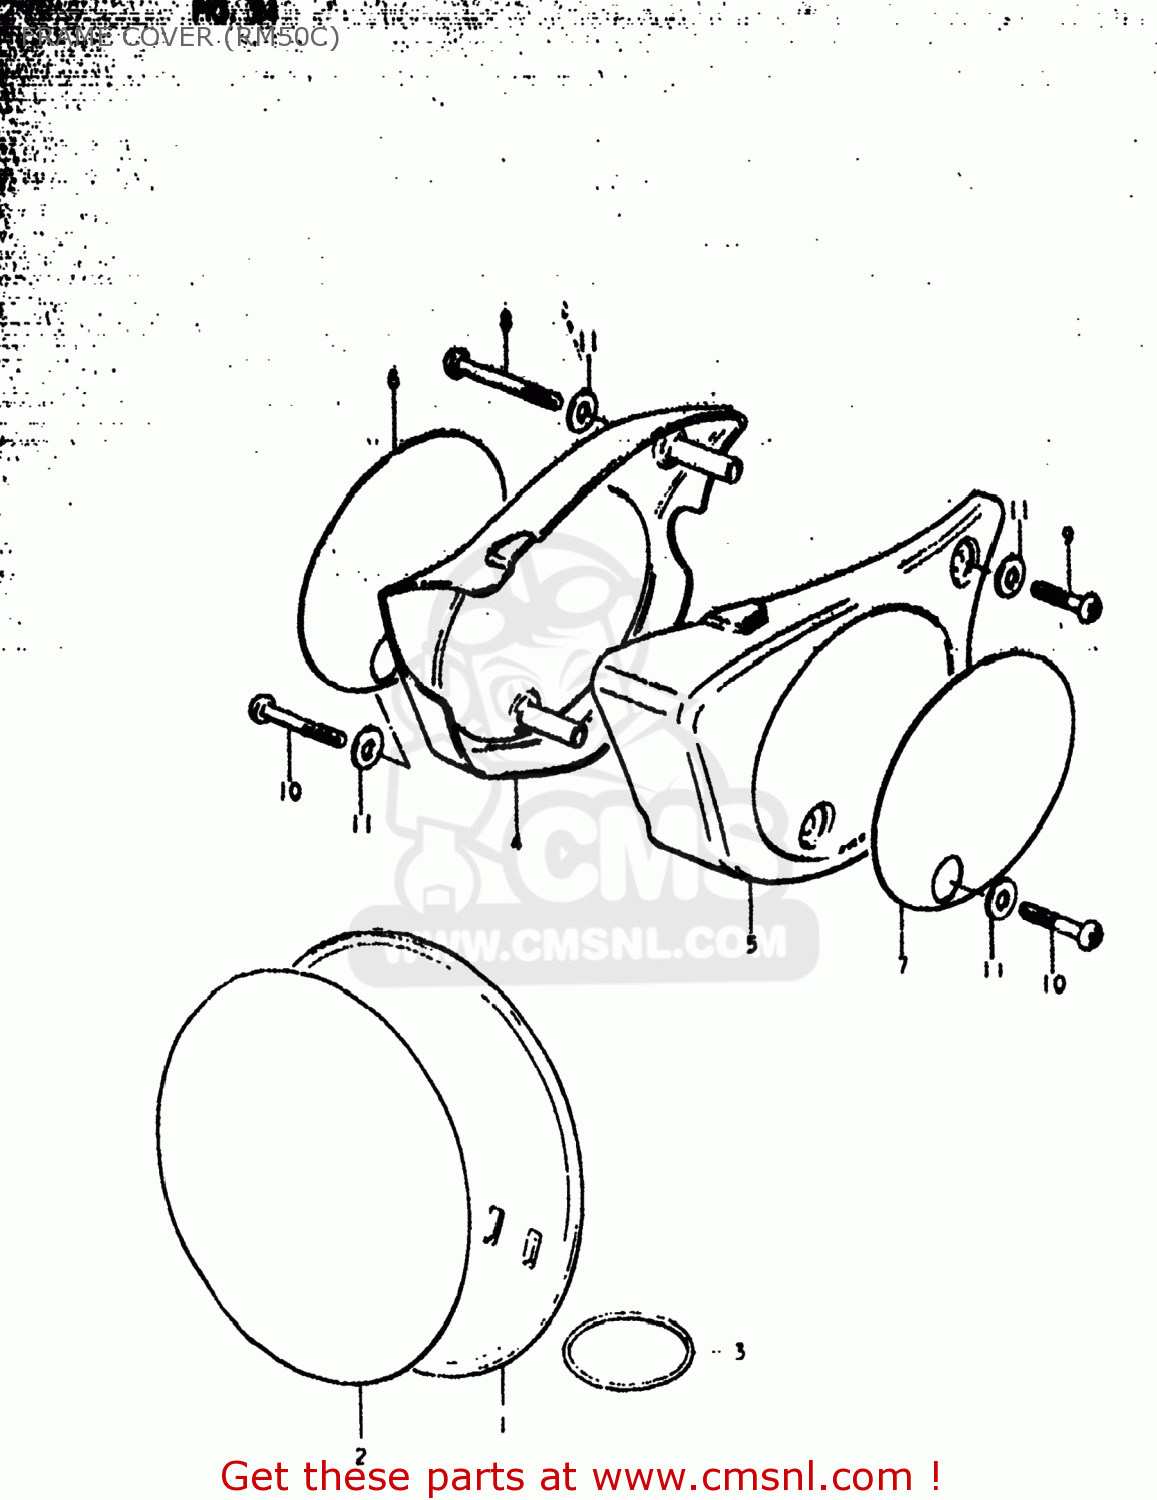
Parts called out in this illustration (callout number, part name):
1	PLATE,NUMBER,FRONT
2	EMBLEM,FRONT NUMBER PLATE
3	O-RING
4	COVER,FRAME,RIGHT
5	COVER,FRAME,LEFT
6	TAPE,FRAME COVER
7	TAPE,FRAME COVER
8	SCREW, NO.1
9	SCREW
10	SCREW
11	WASHER
